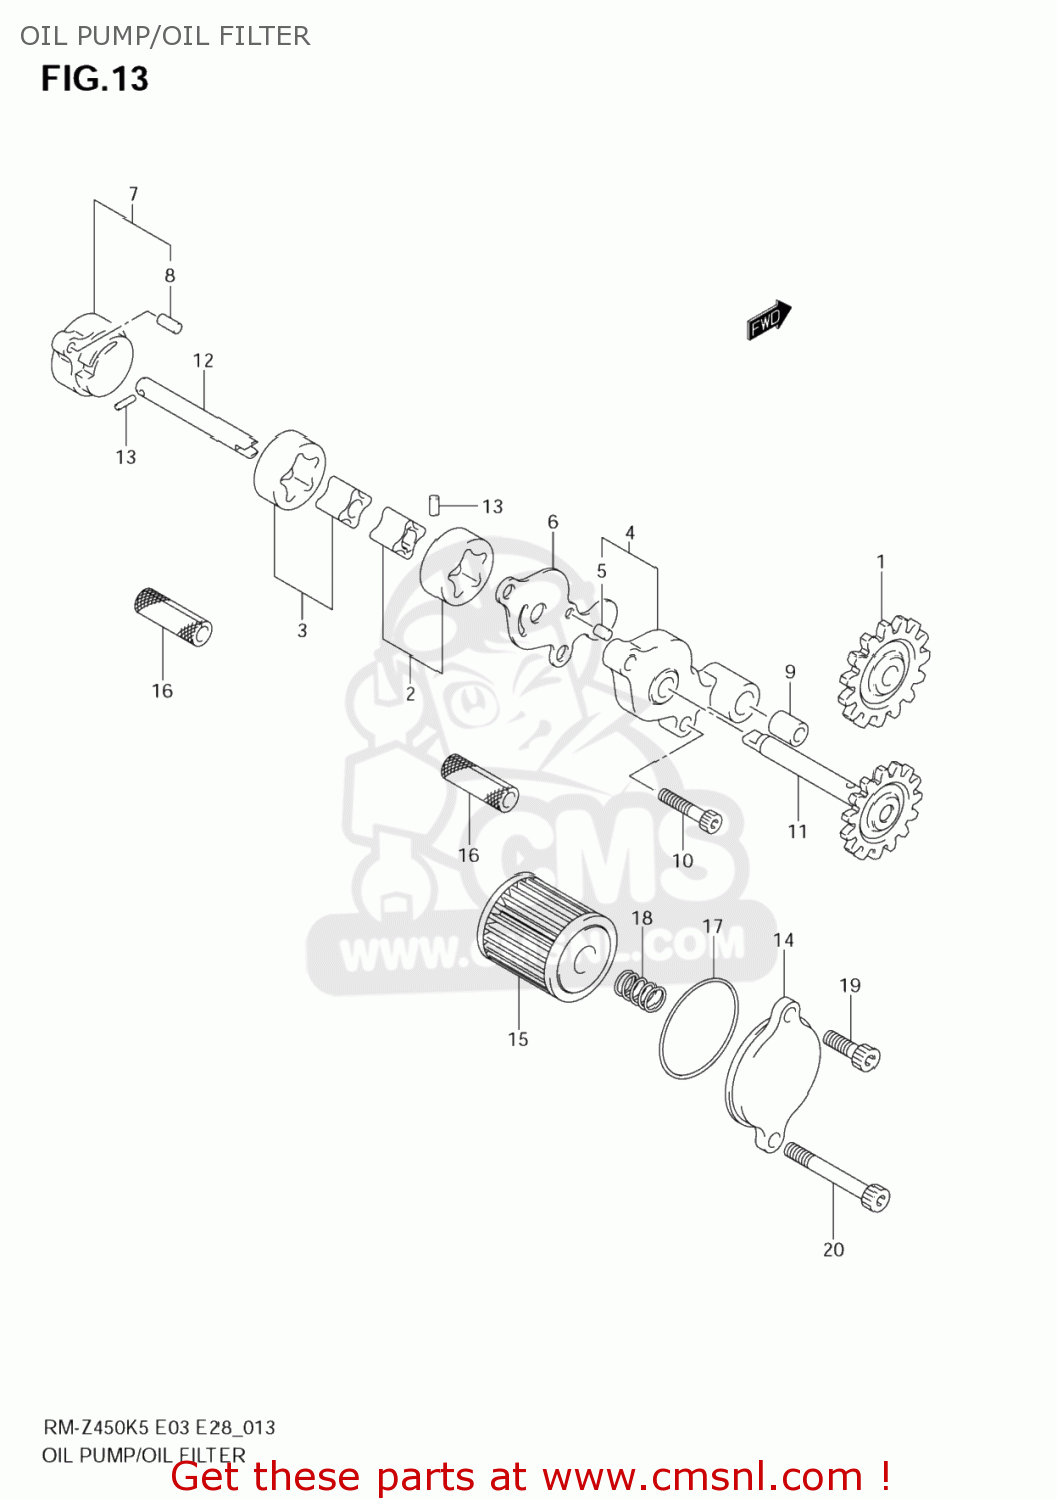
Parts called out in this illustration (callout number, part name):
1	GEAR,OIL PUMP IDLE
2	ROTOR SET,OIL PUMP NO.1
3	ROTOR SET,OIL PUMP
4	COVER,OIL PUMP NO.1
5	PIN
6	PLATE,OIL PUMP NO.1
7	COVER,OIL PUMP NO.2
8	PIN
9	PIN
10	SCREW
11	SHAFT COMP,OIL
12	SHAFT,OIL PUMP NO.2
13	PIN(2.5X11.8)
14	CAP,ENG OIL FILTER OUTER
15	FILTER ASSY,ENGINE OIL
16	STRAINER,OIL
17	O RING(D:2,ID:38.5)
18	SPRING
19	BOLT,OIL FILLE
20	BOLT
